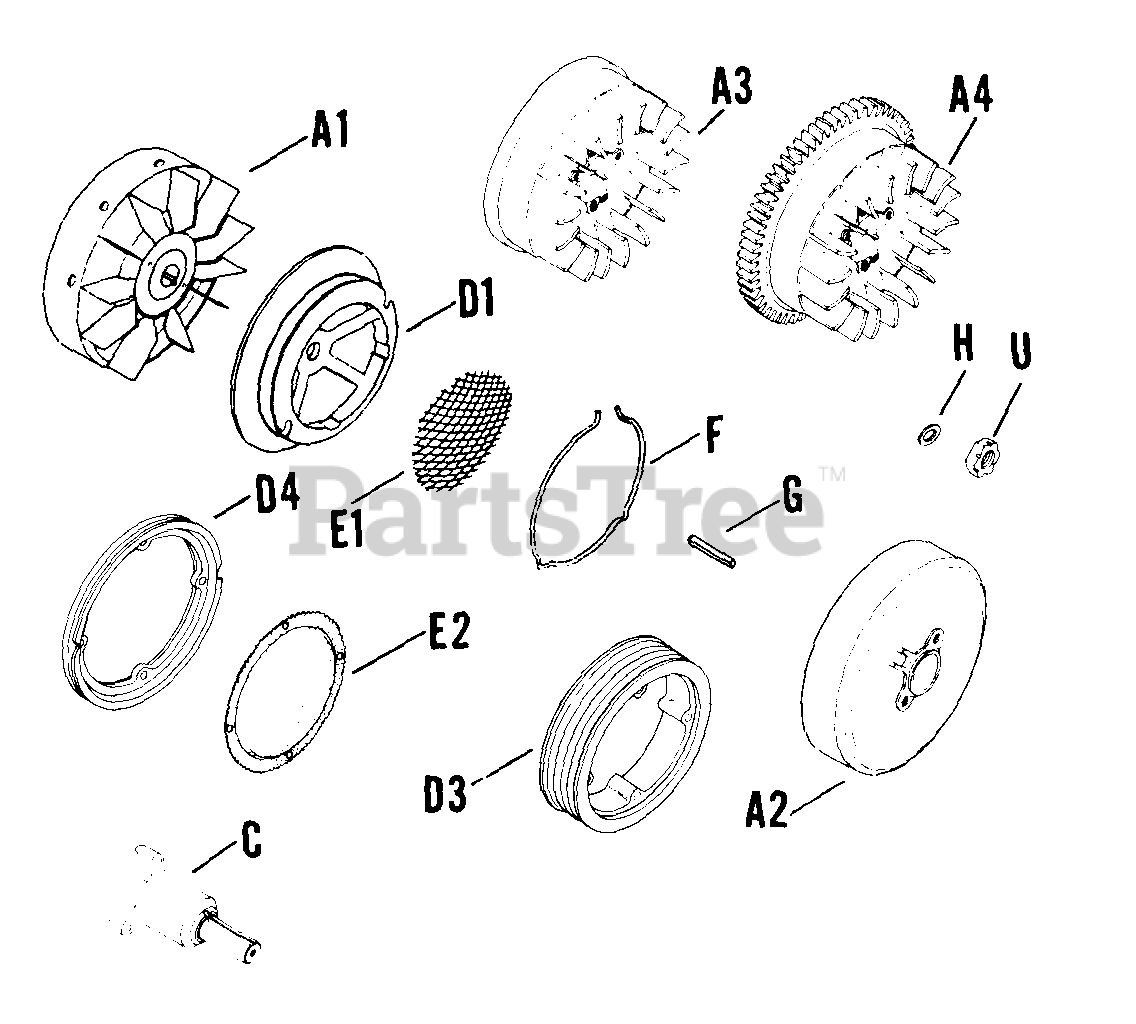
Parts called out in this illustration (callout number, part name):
A3	FLYWHEEL
E2	SCREEN, GRASS
U	NUT - USE 25 100 02
